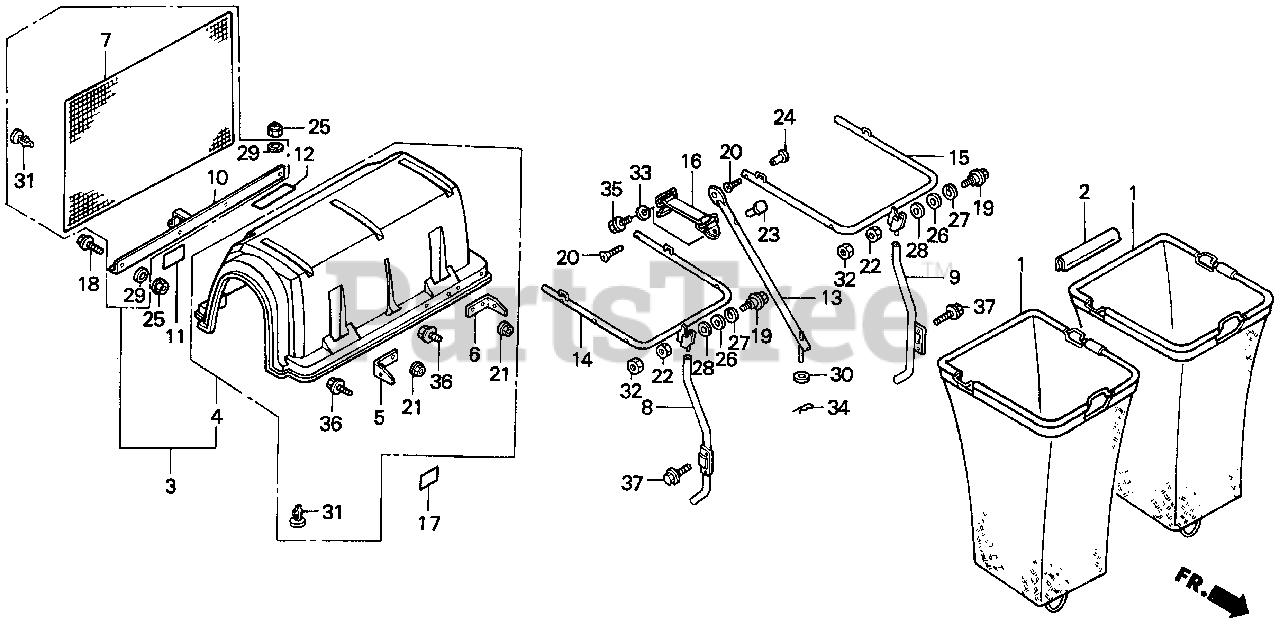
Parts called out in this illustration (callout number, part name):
1	BAG ASSY., GRASS
1	BAG ASSY., GRASS (ENGLISH)
1	BAG, GRASS
2	CLIP, GRASS BAG TUBE (NOT AVAILABLE)
3	HOPPER ASSY., TOP
5	HINGE, HOPPER TOP
6	HINGE, HOPPER TOP
7	SCREEN
8	POST, R. SUPPORT (NOT AVAILABLE)
9	POST, L. SUPPORT
10	STIFFENER, RR. (N/A: SEE ASSEMBLY)
11	LABEL, HOPPER TOP (ENGLISH)
11	LABEL, HOPPER TOP
12	LABEL, HOPPER TOP ROOF (ENGLISH)
13	BRACE, SUPPORT
14	STAY, R. SUPPORT (NOT AVAILABLE)
15	STAY, L. SUPPORT
16	BAND ASSY., HOPPER TOP
19	BOLT, HINGE (10MM)
20	SCREW, FLAT (8X45)
21	NUT, FLANGE (6MM)
22	NUT, AXLE (10MM)
23	NUT, PIPE (6MM)
24	NUT, PIPE (8MM)
26	WASHER, THRUST (14MM)
27	WASHER, SPRING (14MM)
30	WASHER (3/8")
31	CLIP, SCREEN
33	WASHER, PLAIN (10MM)
34	PIN, LOCK (10MM) Use from Frame SN 2149606 to 2149605.
35	BOLT, FLANGE (6X16) Use from Engine SN 2056820.
36	BOLT, FLANGE (6X18)
37	BOLT, FLANGE (8X20)
